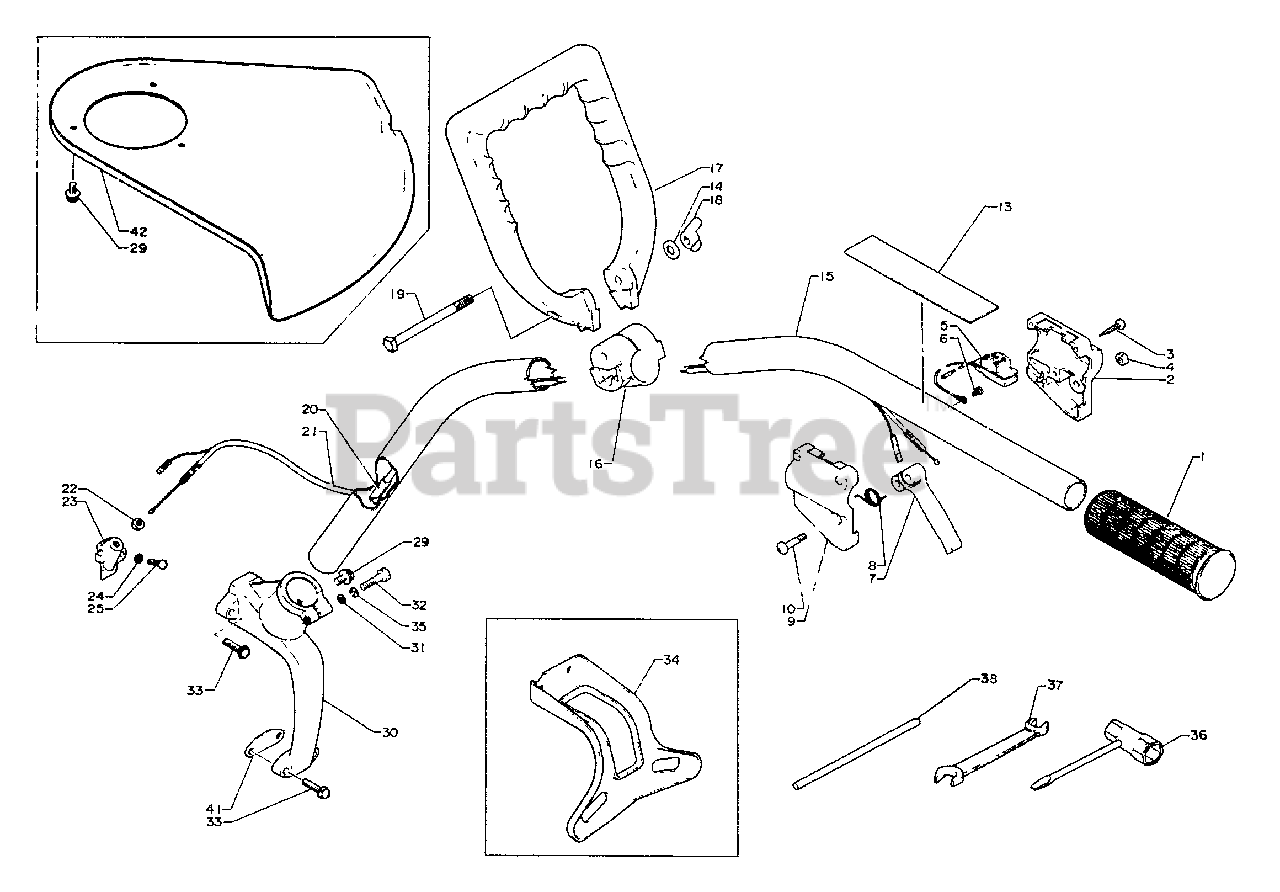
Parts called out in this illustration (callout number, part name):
1	GRIP
2	BRACKET, TRIGGER
3	SCREW - 4X25
4	LOCKNUT - 5
5	IGNITION SWITCH ASSY
6	SCREW - 4X8
7	TRIGGER, THROTTLE
8	SPRING, TRIGGER
9	BRACKET - LEFT
10	SCREW - 5X30
13	LABEL - CAUTION
14	WASHER - 6
15	PIPE, MAIN
16	BRACKET, HANDLE
18	NUT - 6 -- BUTTERFLY
19	BOLT
20	COVER, THROTTLE CABLE
21	CABLE, THROTTLE
23	BRACKET, THROTTLE CABLE
24	WASHER - 4
25	SCREW - 4X12
29	SCREW - 5X10
30	BRACKET
31	WASHER - 5
32	BOLT - 5X25
33	SCREW - 5X20
34	STAND
35	LOCKWASHER - 5
36	T-WRENCH
37	SPANNER - 8X10mm
38	LOCKING TOOL
41	SPACER
42	SHIELD, DEBRIS
